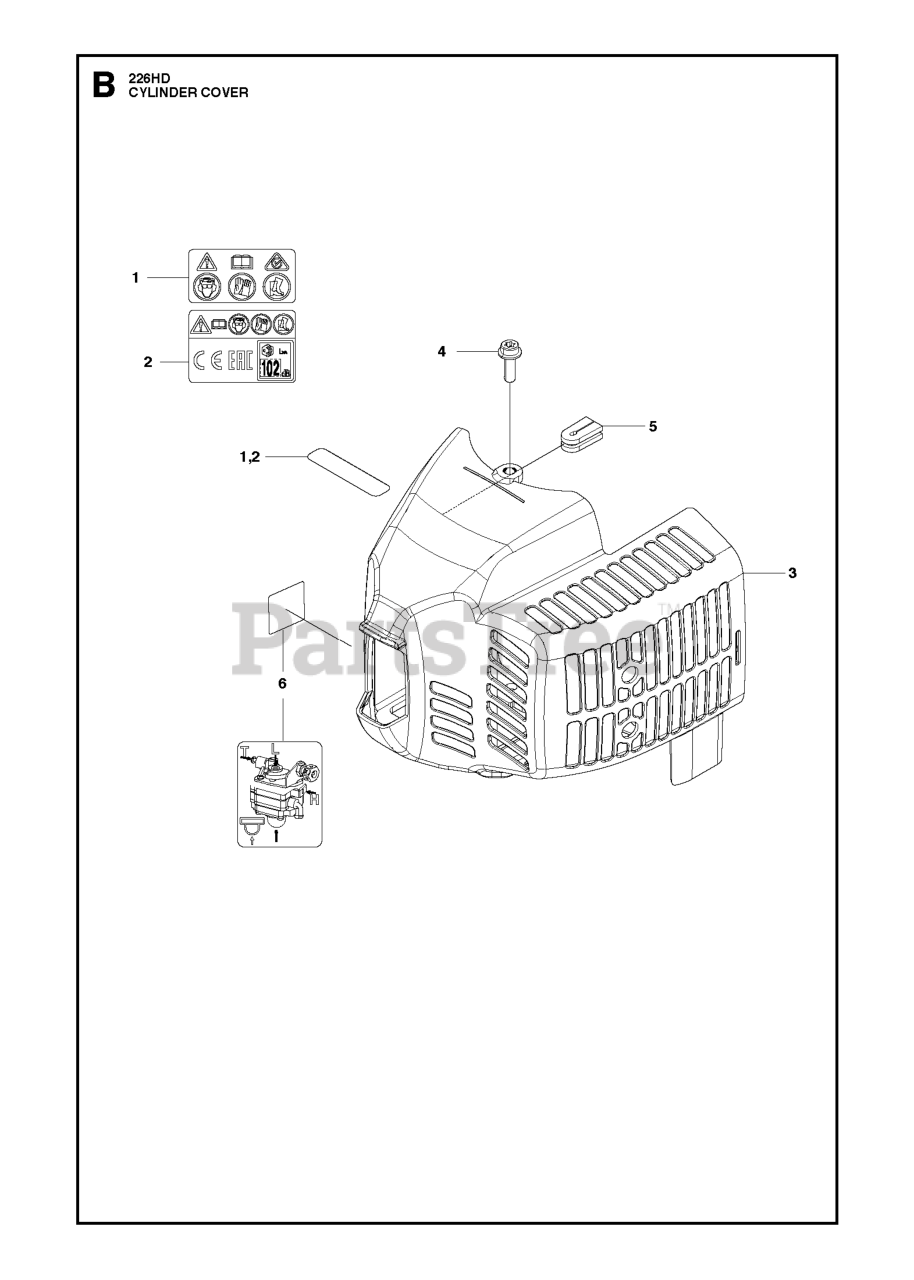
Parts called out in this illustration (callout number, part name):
1	DECAL
3	COVER ENGINE
6	DECAL ADJ LOCATION
